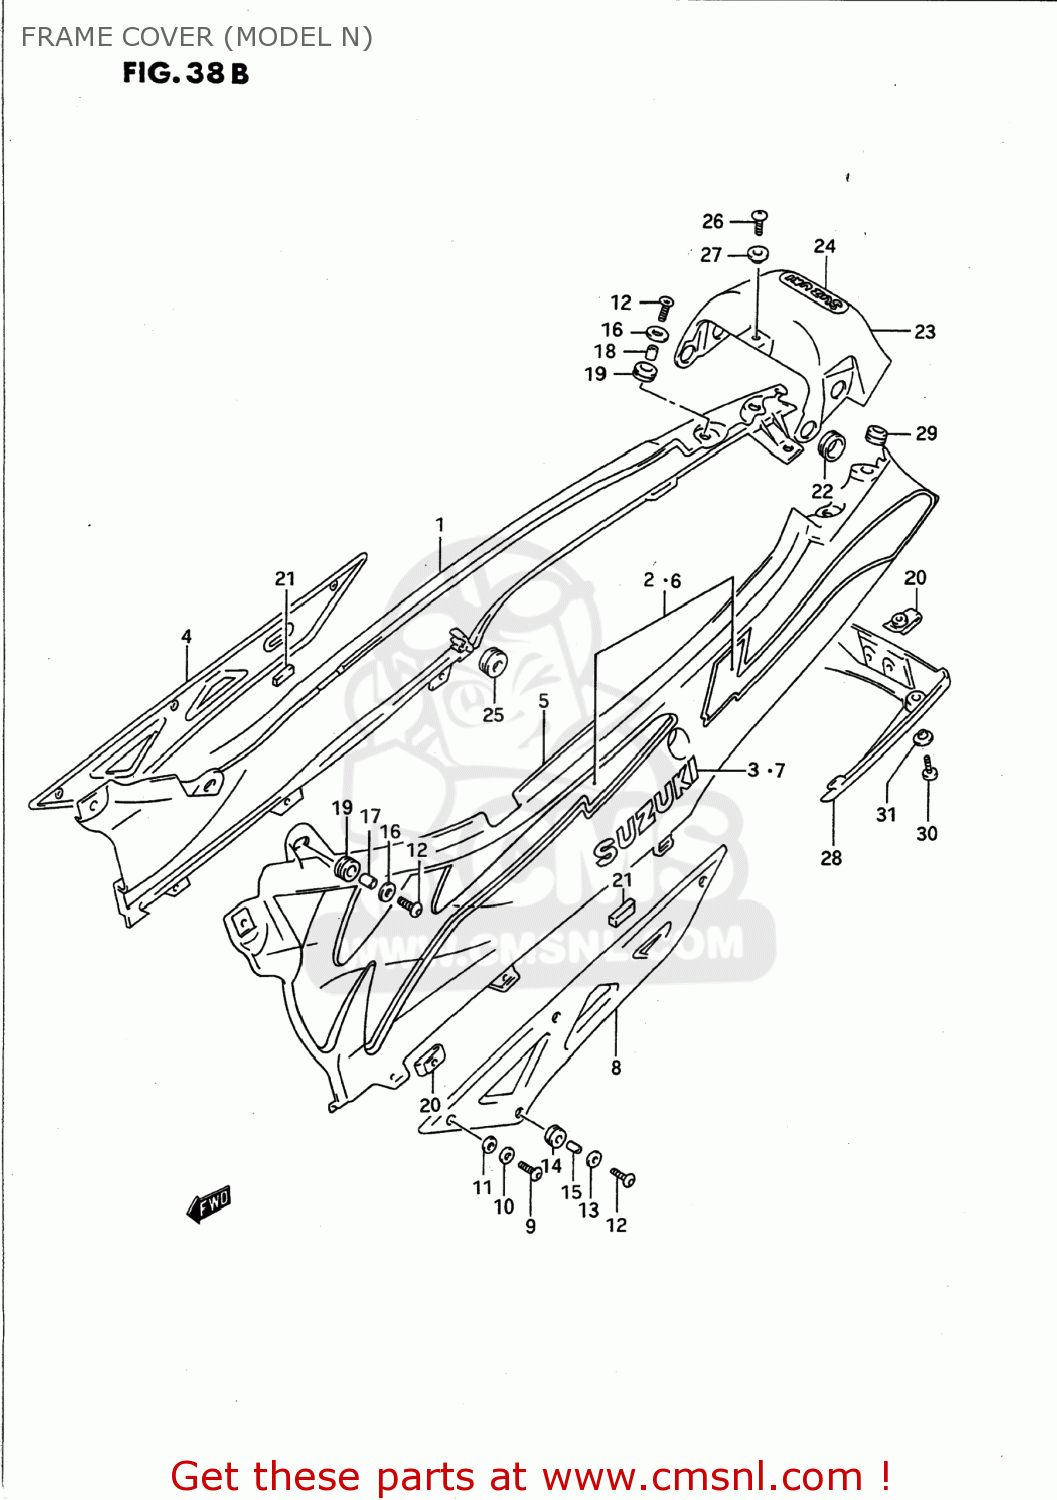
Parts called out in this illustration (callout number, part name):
1	COVER,FRAME,RIGHT
2	TAPE SET,FRAME COVER STRIPE
3	EMBLEM,RIGHT (SILVER)
4	COVER,FRAME LWR,R
5	COVER,FRAME,LEFT
6	TAPE SET,FRAME COVER STRIPE
7	EMBLEM,RIGHT (SILVER)
8	COVER,FRAME LWR,L
9	SCREW(6X16)
10	WASHER (6.7X16X1.8)
11	WASHER (5.5X16X1)
12	SCREW(6X16)
13	WASHER(6.5X22X1.6)
14	CUSHION
15	SPACER(6.2X8.3X6.1)
16	WASHER
17	SPACER (6.1X9X9)
18	SPACER(6.1X9X7.5)
19	CUSHION
20	PLATE,FRAME COVER
21	CUSHION,FRAME COVER LWR
22	GROMMET
23	COVER,FRAME,CENTER
24	EMBLEM,FRAME COVER,CENTER
25	CUSHION
26	SCREW 6X10
27	WASHER
28	COVER,FRAME RR
29	CUSHION
30	SCREW
31	WASHER
